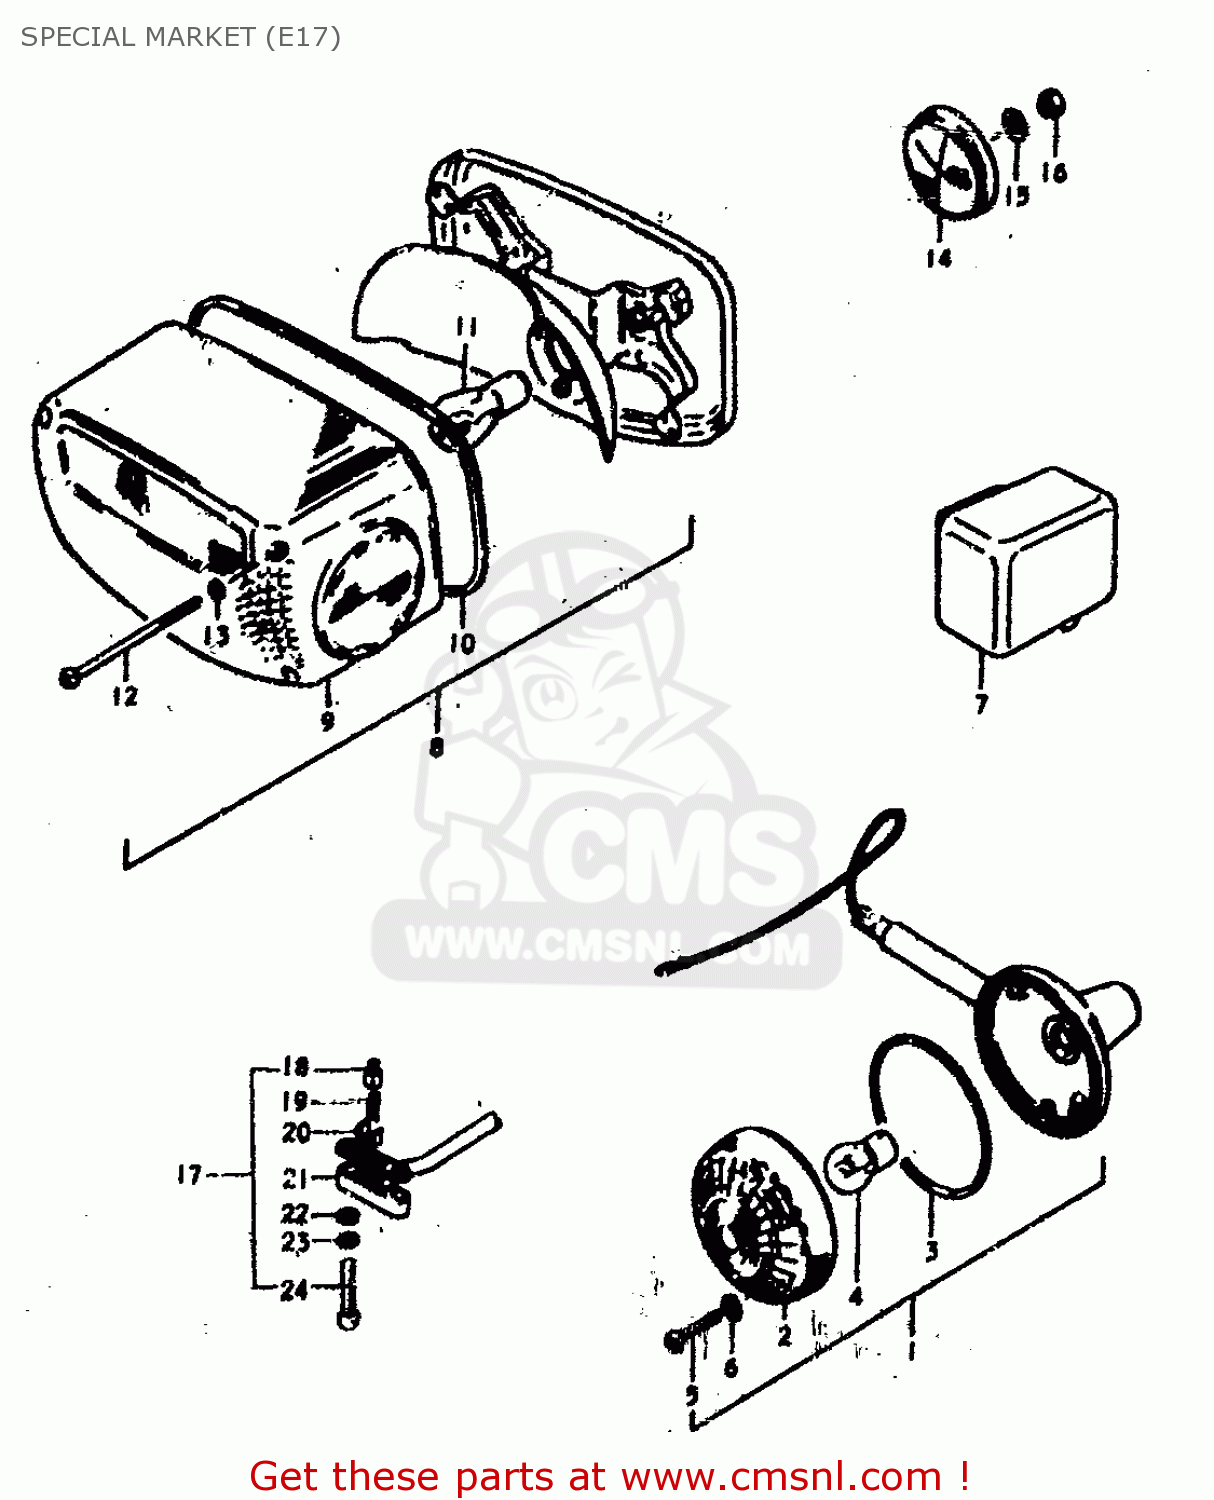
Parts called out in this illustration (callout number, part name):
1	LAMP ASSY, REAR TURN SIGNAL
2	LENS
3	GASKET (NAS)
4	BULB 12V 21W
5	SCREW
6	GASKET (NAS)
8	LAMP ASSY,REAR COMBINATION
9	LENS
10	GASKET (NAS)
11	BULB 12V21/5W
12	SCREW (4X55)
13	GASKET (NAS)
14	REFLECTOR,REFLEX
15	SPACER
16	NUT
17	SWITCH ASSY,STOP
18	HOLDER
19	SPRING
20	PLATE
21	COVER,FR BK TERMINAL BASE
22	WASHER
23	LOCK WASHER
24	SCREW
